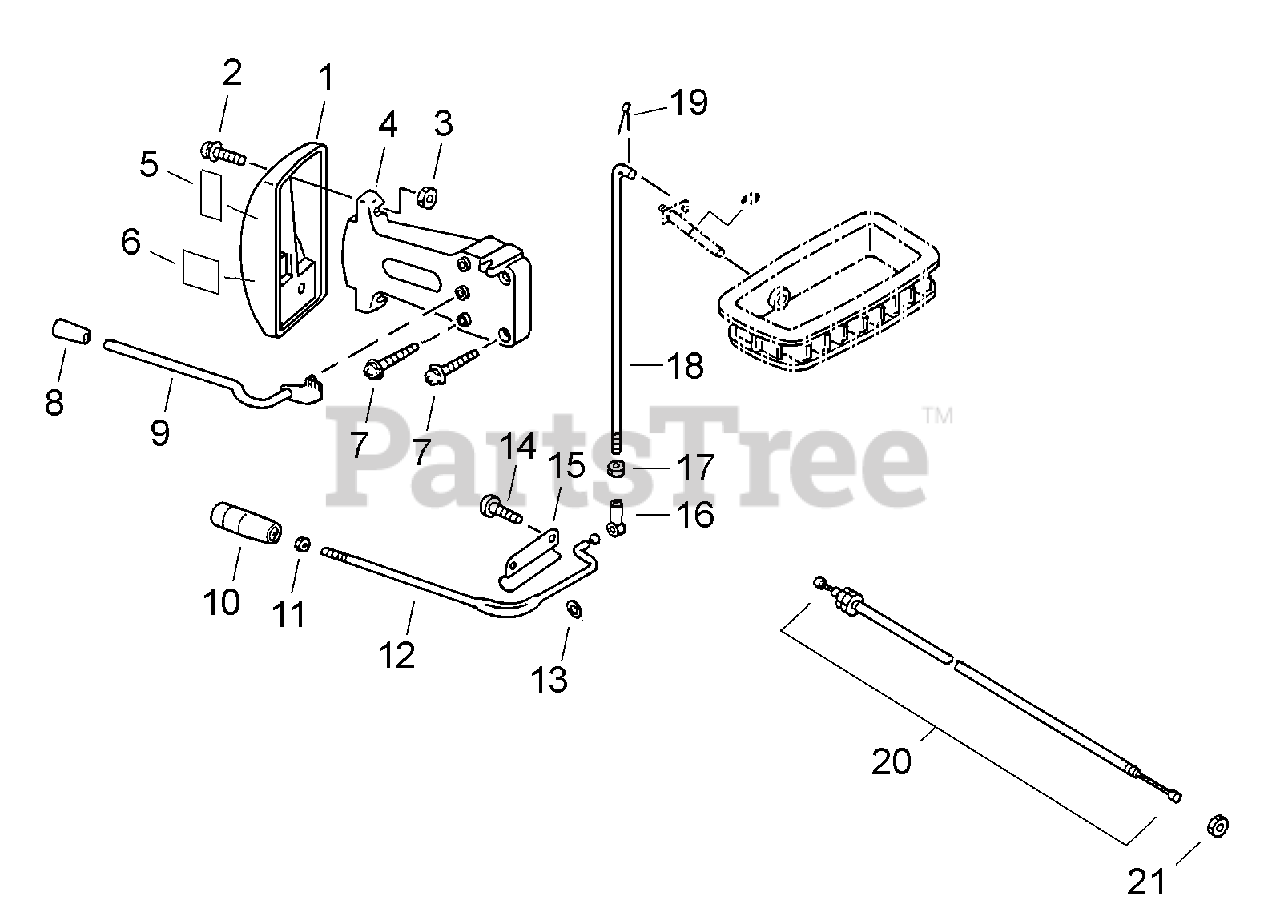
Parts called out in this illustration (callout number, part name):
1	DIAL, RATE CONTROL
2	SCREW - 5X25
4	BRACKET, DIAL
5	LABEL - THROTTLE
6	LABEL - STOP
7	SCREW - 5X25
8	KNOB, THROTTLE CONTROL
9	LEVER, THROTTLE CONTROL
12	LEVER, SHUTTER CONTROL
13	WASHER - 8
14	SCREW - 5X14
15	BRACKET, LEVER
16	CONNECTOR
18	ROD, CONTROL LEVER
19	PIN, SPLIT - 1.8×18
20	CABLE, THROTTLE
